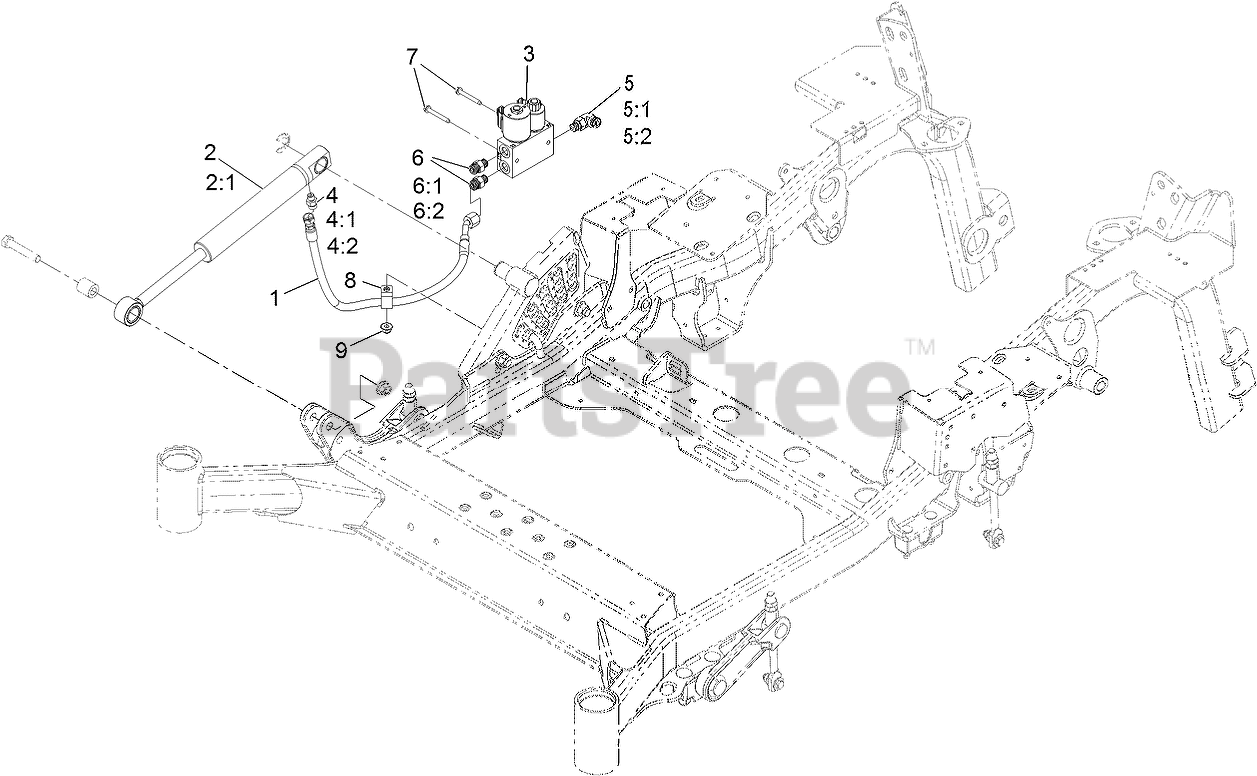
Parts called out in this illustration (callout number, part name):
1	HOSE ASM
2	CYLINDER-LIFT
2:1	CYL Repair Kit
3	DECK LIFT VALVE ASM
4	FITTING-HYD, STRAIGHT
4:1	O-RING
4:2	O-RING
5	FITTING-ELBOW, 90 DEG
5:1	O-RING
5:2	O-RING
6	FITTING-STRAIGHT
6:1	O-RING
6:2	O-RING
7	SCREW-HWHTF
8	CLIP-LOOM
9	NUT-HF, NI
